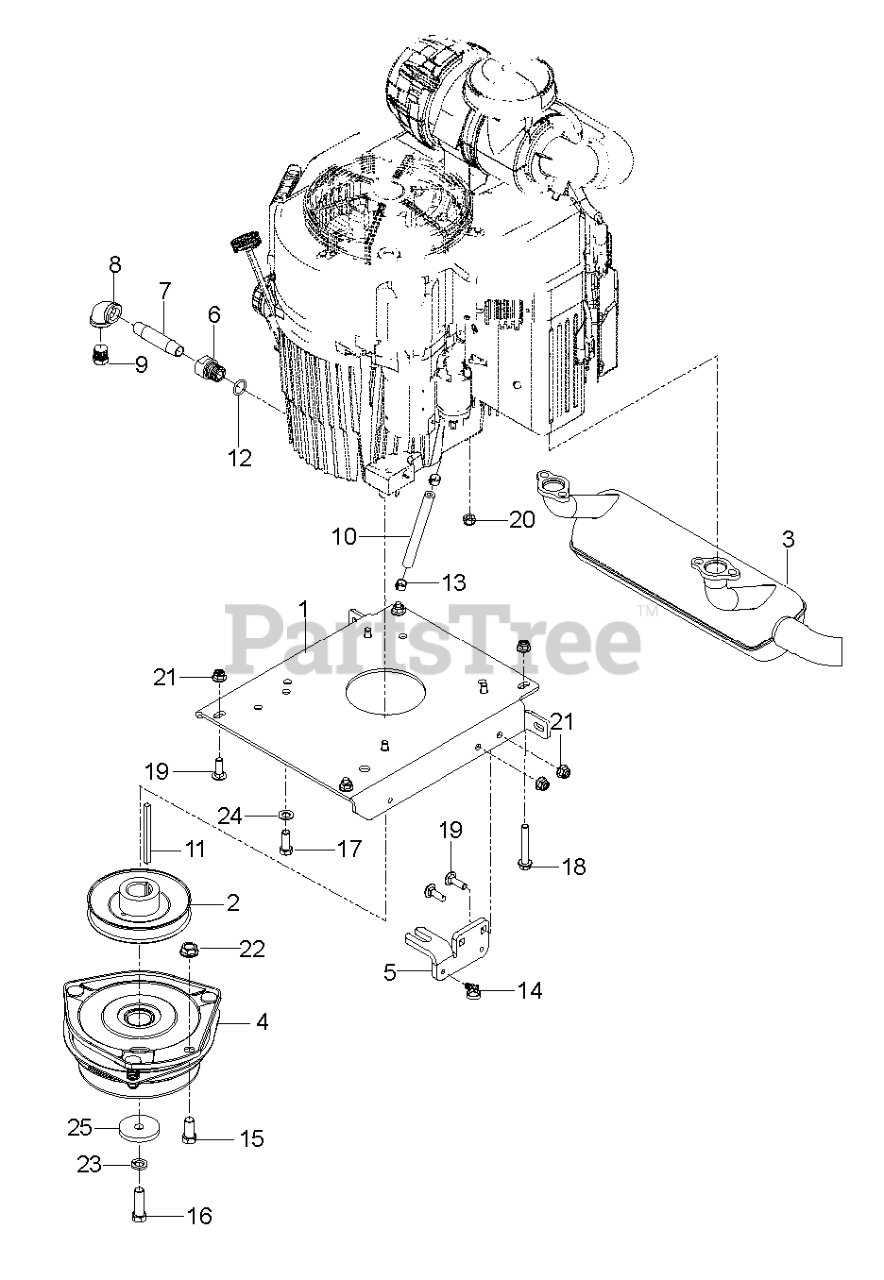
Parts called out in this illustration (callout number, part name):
1	PLATE.ENGINE.BLACK
2	PULLEY, ENGINE
3	MUFFLER, 29HP KAW FX751V-850V
4	CLUTCH, GT3.5
5	STOP, CLUTCH, OGURA
6	ADAPTER, OIL DRAIN
7	PIPE NIPPLE 3/8 X 3
8	90 DEG.ELBOW 3/8NPT
9	PLUG, DRAIN 3/8 NPTF
10	HOSE.1/4".LOW.PERM.FUEL.LN.14"
11	KEY, 1/4 SQ X 3.5
13	HOSE CLAMP
14	TIE WRAP, 8-3/8", W/CLIP
15	BOLT FIN HEX 7/16-14 X 1
16	CLUTCH BOLT7/16-20X1.5GR5.96HR
17	HCS 3/8-16X1.GRD.5.ZD
18	HHFS 5/16-18 X 2.25 GD 5
19	RHSNB 5/16C X 1
20	NUT M8-1.25 TOP NYL GR10 ZD
21	5/16-18 NYLOC FLANGE NUT
22	NUT 7/16C WHIZ
23	WASHER 7/16 LOCK
24	WASHER, 3/8 DISC SPRING SPEC
25	BLADE WASHER
